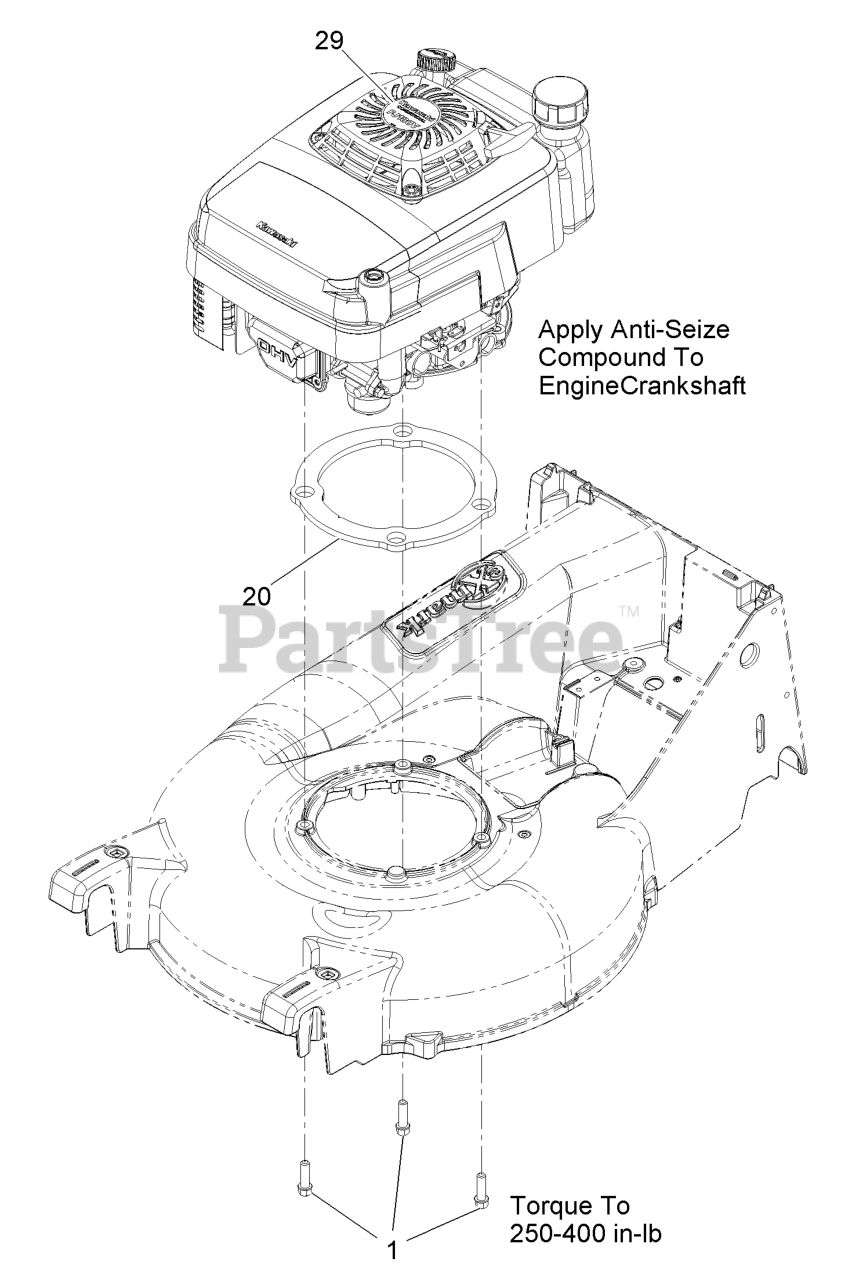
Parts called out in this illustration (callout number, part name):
1	SCREW-TAPTITE
20	GASKET,DECK
29	DECAL-RECOIL
